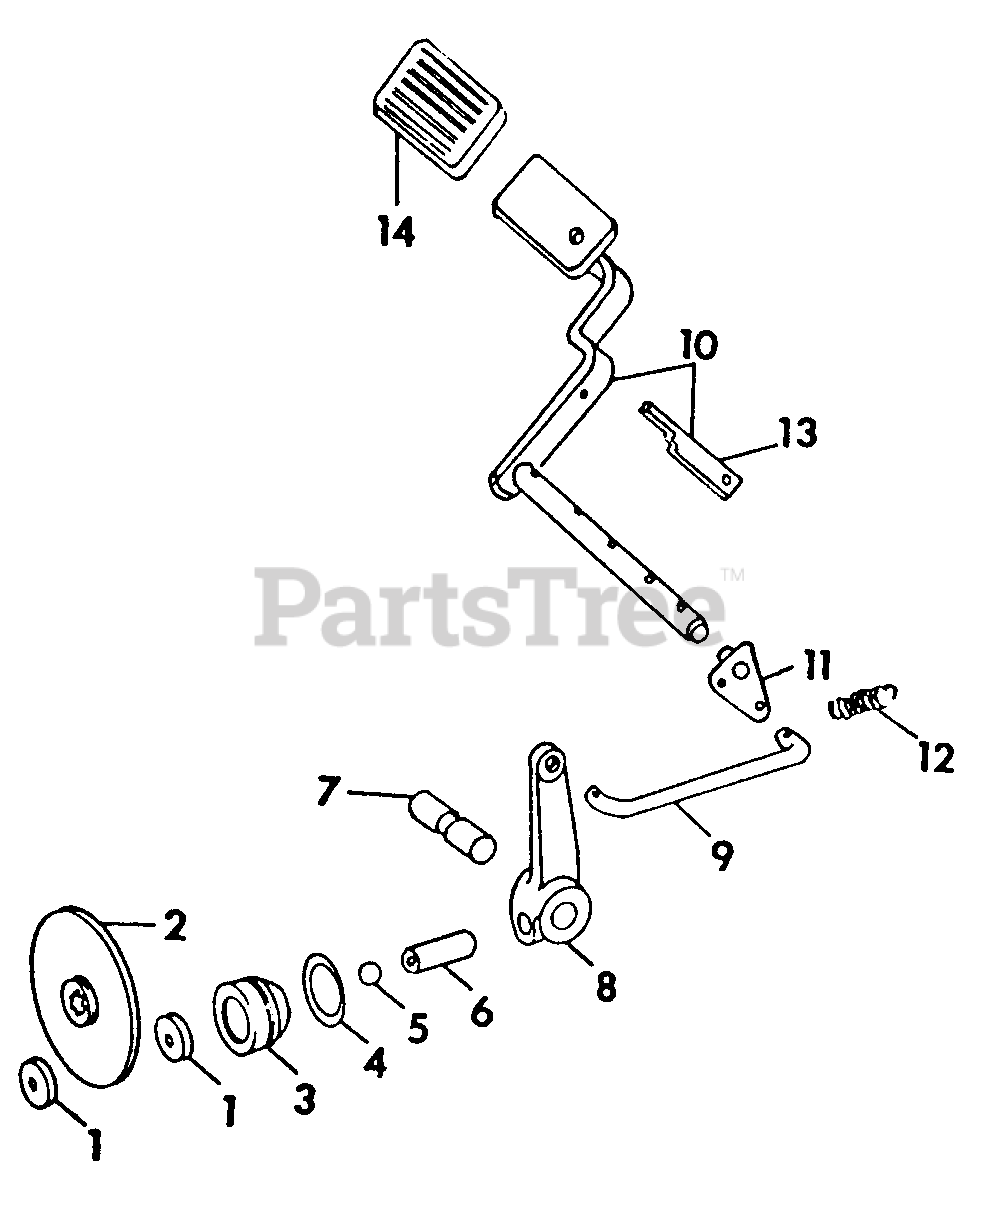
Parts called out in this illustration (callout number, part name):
1	Disc, Brake Lining
2	Disc Assy, Brake
3	Retainer, Brake Lining
4	O-Ring, 1-3/16 X 1-3/8 X 3/32
5	Ball, 9/16 Cr Stl
6	Rod, Brake Push
7	Pin, Brake Lever Pivot
8	Lever, Brake
9	Rod, Brake
10	Pedal Assy, Clutch & Brake
11	Arm, Clutch & Brake Pedal
12	Spring, Clutch Pedal Return
14	Pad, Pedal
